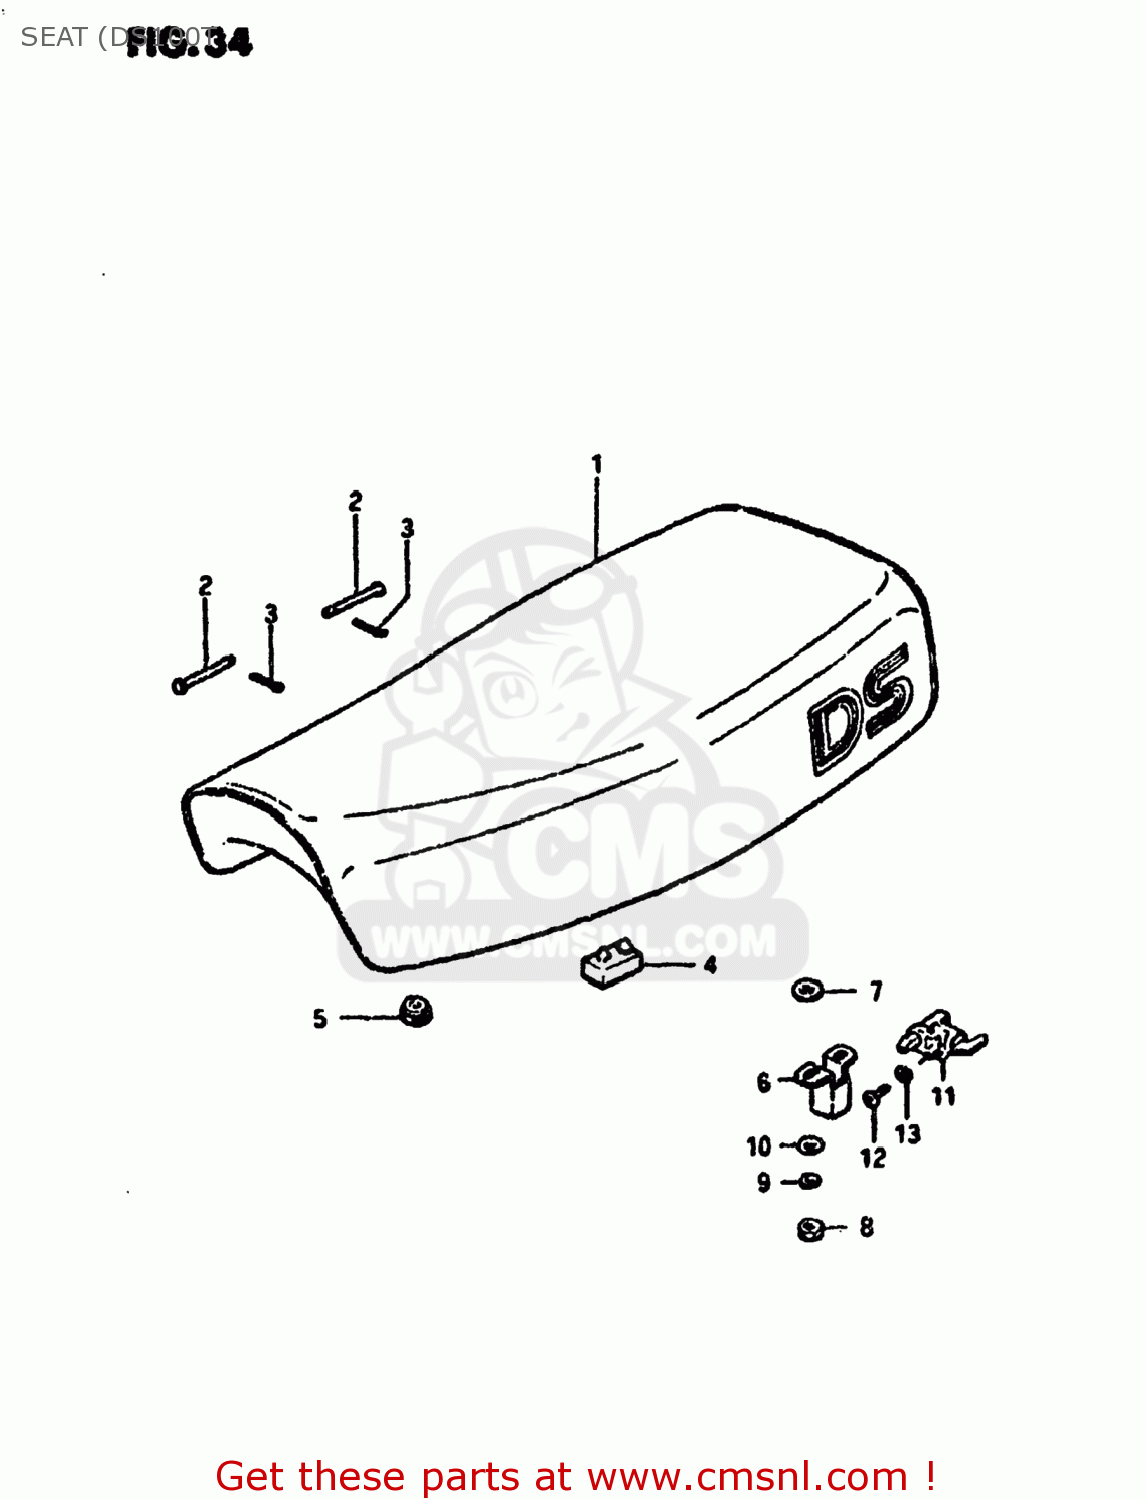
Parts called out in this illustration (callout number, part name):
1	SEAT ASSEMBLY
2	PIN
3	PIN
4	CUSHION
5	CUSHION
6	PLATE,CLAMP GUIDE
7	WASHER(8.5X18X1)
8	NUT
9	LOCK WASHER
10	WASHER
11	LOCK ASSEMBLY,SEAT
12	SCREW
13	LOCK WASHER
